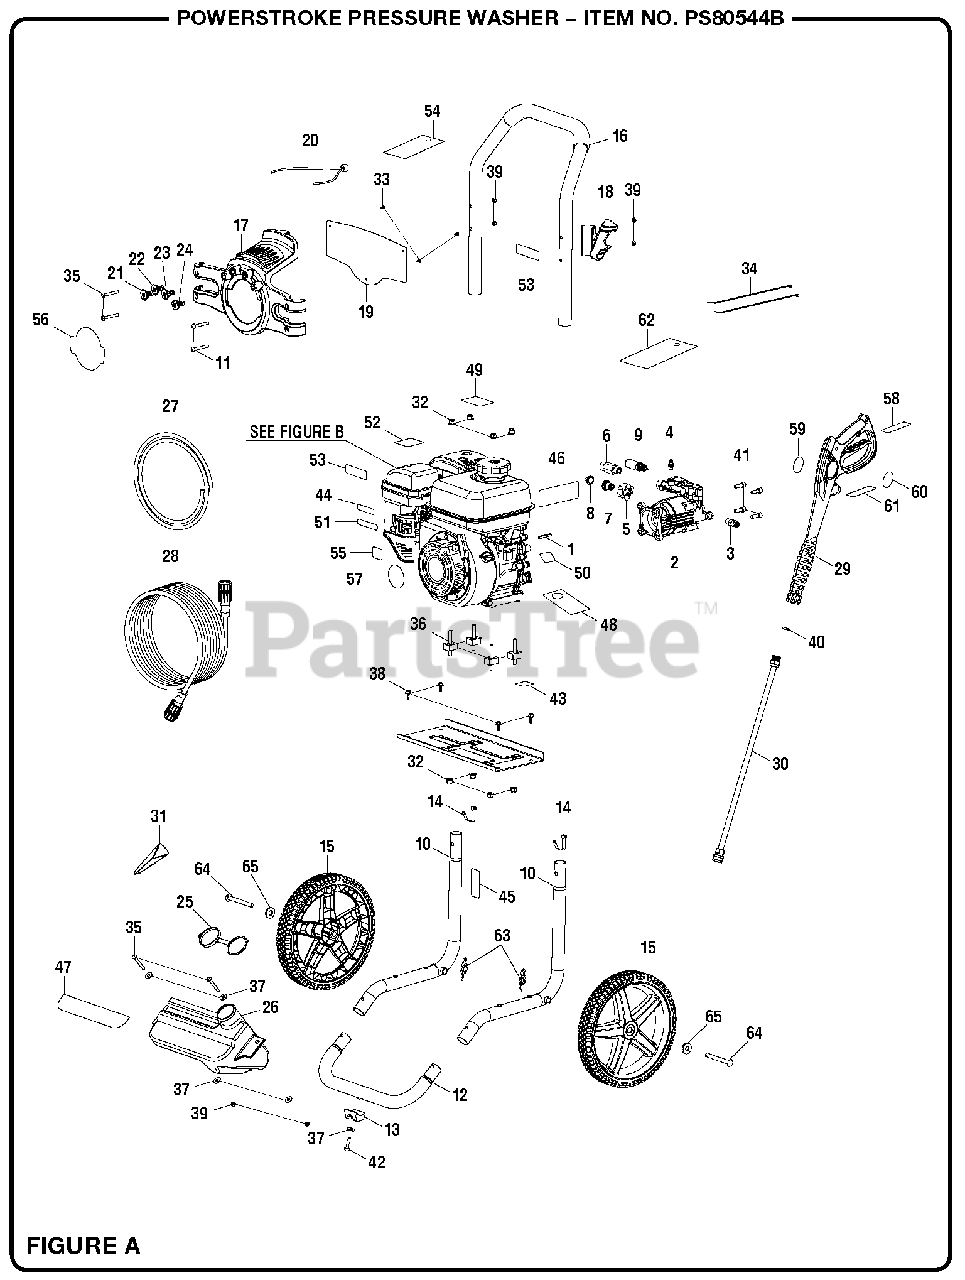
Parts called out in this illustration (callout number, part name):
1	Output Shaft Key
2	Pump
3	Thermal Release Valve
4	Soap Injector Kit
5	Inlet Filter Adapter Insert
6	Outlet Tube
7	Inlet Filter Connector
8	Inlet Filter Screen
9	Unloader Valve Assembly
10	Main Frame Assembly
11	Screw (M6 x 48 mm, Phillips Pan Hd.)
12	Front Frame Assembly
13	Rubber Foot
14	Handle Spring Clip
15	Wheel (12 in.)
16	Handle Assembly
17	Hose and Nozzle Holder Assembly
18	Wand Holder
19	Instruction Panel
20	Bungee Cord and Bead Assembly
21	0deg Deg Nozzle
22	25deg Deg Nozzle
23	40deg Deg Nozzle
24	Soap Nozzle
25	Soap Tank Cap
26	Soap Tank
27	Chemical Siphon Tube
28	Hose (25 ft.)
29	Trigger Handle Assembly
30	Wand Assembly
32	Flange Lock Nut (M8)
33	Screw (#6-20 x 3/8 in.)
35	Screw (M6 x 48 mm, T-30 Torx Hd.)
36	Engine Isolator
37	Washer (1/4 in.)
38	Bolt (M6 x 16 mm, Flange Hd.)
39	Lock Nut (M6)
41	Bolt (5/16-24 x 23 mm, Hex Soc. Hd.)
42	Screw (M6 x 25mm, T-30 Torx Pan Hd.)
43	Add Oil Label
44	Choke Label
45	Combustion Label
46	Danger Label
47	Detergent Tank Label
48	Oil Dipstick Hang Tag
49	E85 Label
50	Engine Switch Label
51	Fuel Label
52	Hot Surface and Exhaust Label
53	Inquiries Label
54	Nozzle Hangtag
55	On/Off Label
56	Performance Label
57	Recoil Label
58	Trigger Handle Warning Label (Fr/Sp)
59	Powerstroke Trigger Wand Logo Label
60	Trigger Handle Warning Label (En)
61	Trigger Handle Specifications Label
62	Danger Hang Tag
63	Ring Clip
65	Washer (1/2 in.)
